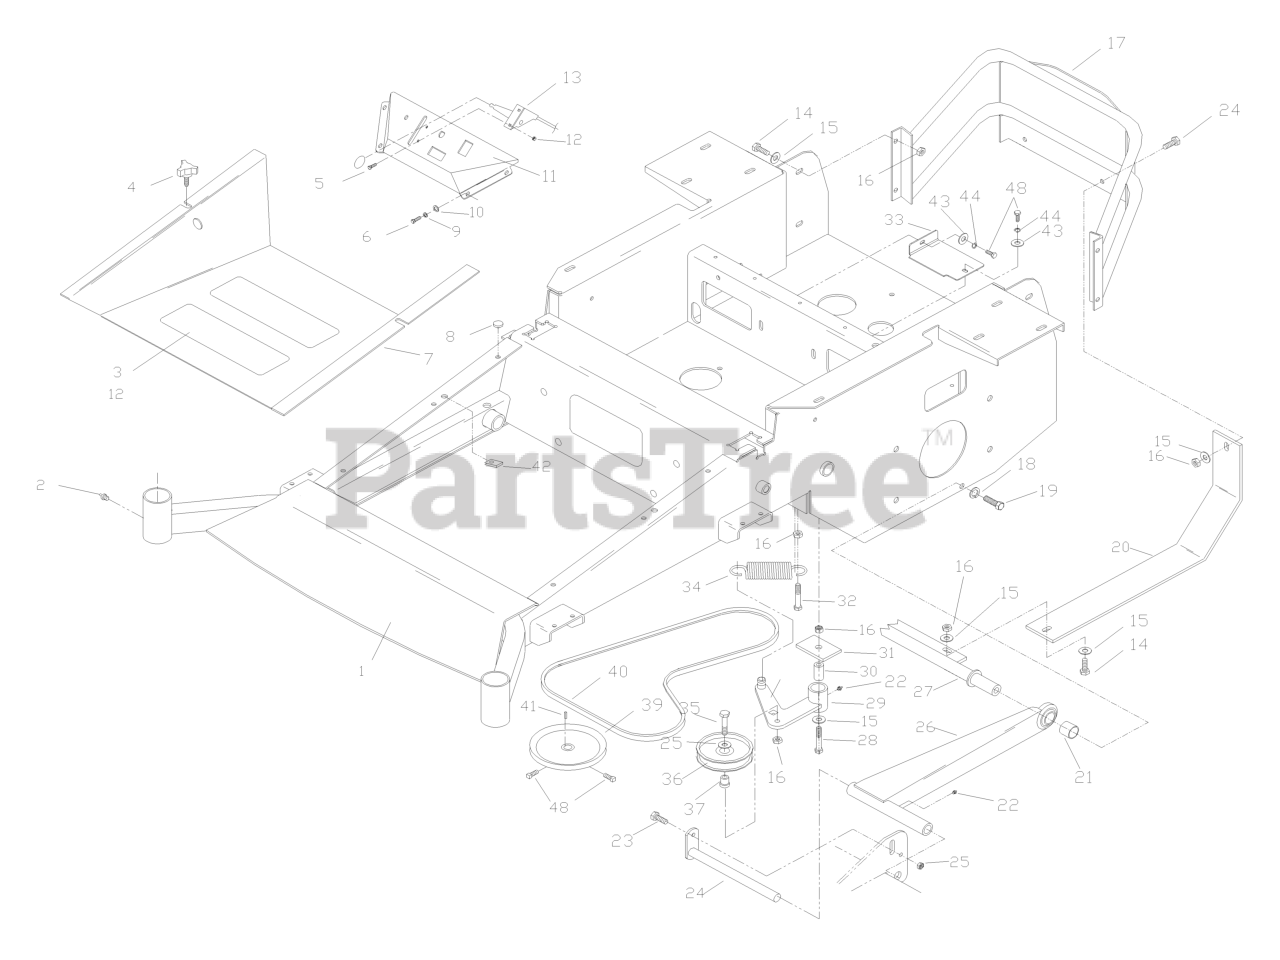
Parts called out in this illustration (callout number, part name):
1	MAIN FRAME W/DECALS
1	FRAME 52" & 61"
2	ZERK
3	ANTI-SKID PAD
4	KNOB W/STUD
5	HCS #10-24 X 1/2
6	SCREW 1/4 X 5/8
7	FOOT PLATE WIDMT
8	GROMMET, BUMPER
9	LOCKWASHER 1/4"
10	WASHER 1/4 FLAT
11	CONSOLE W/DECALS
12	NUT 10-24 NYLOC
13	THROTTLE CONTROL W/BALL KNOB
14	HCS 3/8-16X1.GRD.5.ZD
15	WASHER 3/8 FLAT
16	NUT 3/8C CENTERBLOCK
17	REAR GUARD
18	WASHER 7/16 LOCK
19	HEX SCREW 7/16-14 X 1 GR8
20	SKID PLATE
21	SPACER, STRUT
22	ZERK
23	HCS 5/16C X 3/4
24	PIVOT PIN
25	NUT 5/16C CENTERLOCK
26	STRUT
27	CROSS SHAFT WLD 72
27	CROSS SHAFT WLDMT
28	HCS 1/2C X 3 1/4
29	IDLER ARM WLDT
30	PIVOT BUSHING
32	HCS 3/8C X 1 1/2
33	IDLER COVER
35	HCS 3/8-16 X 1 3/4 GR5
36	IDLER PULLEY
37	BUSHING, IDLER FLANGE
38	SCREW 5/16C X 5/8 SQ HEAD
40	PUMP BELT
41	KEY 5 MM SQ X 25 MM
42	U-CLIP 5/16-18 NUT RETAINER
43	WASHER 5/16 FLAT
44	WASHER.LOCK.HVY.HLCL.SPR.5/16
48	HCS 5/16C X 1
